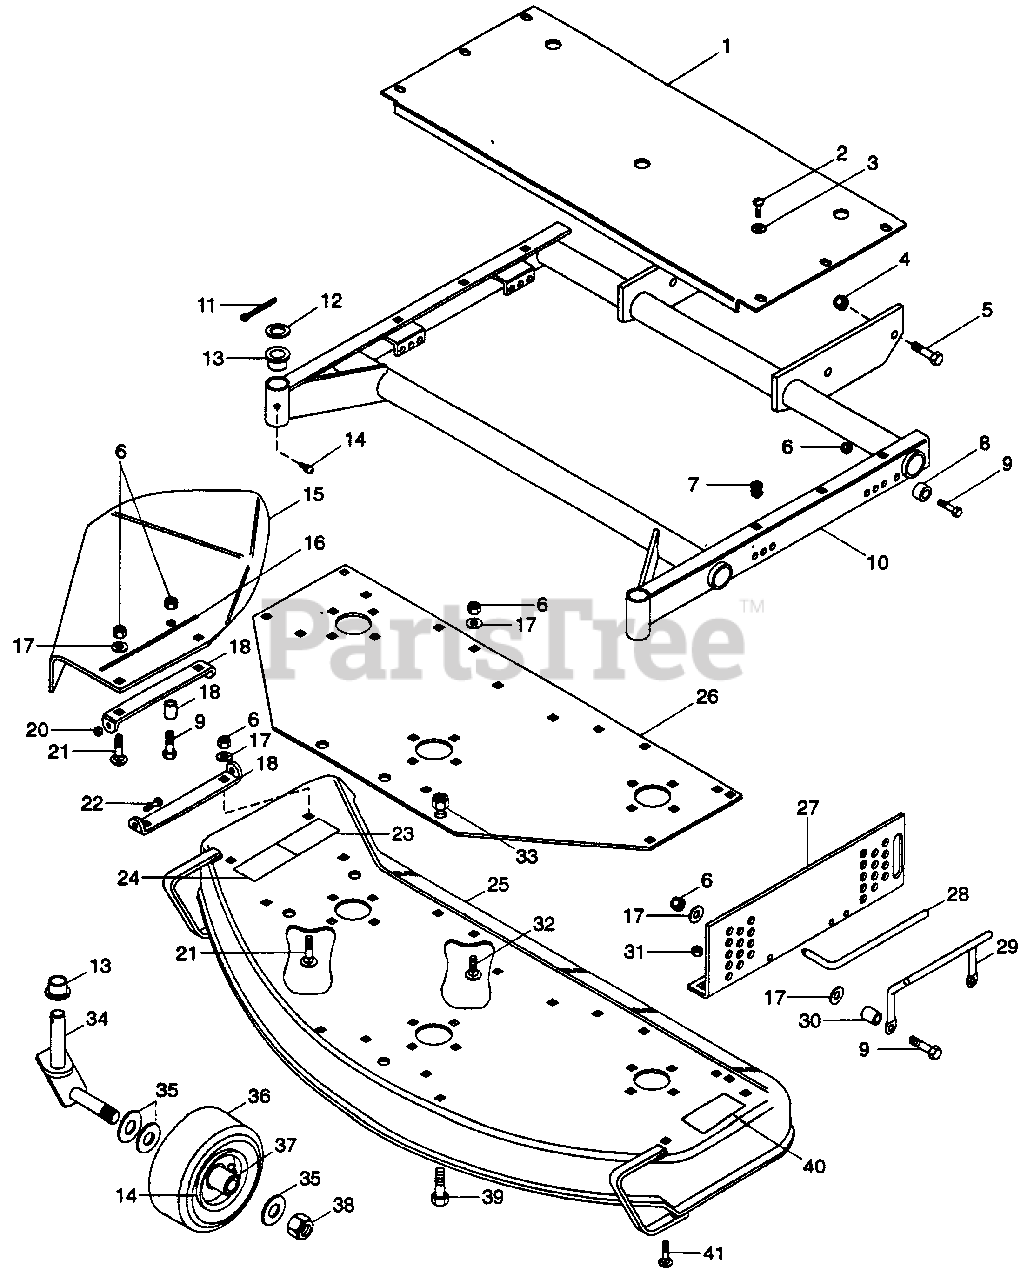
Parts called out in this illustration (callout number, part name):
1	GRD, 50" MOWER BELT
2	SCR-TAP .25-20 X .50 HXSLHD PL
3	WSHR-FL-STL .281 X .62 X .065
4	NUT-LK-NYL .625-11 PL
5	BLT-HEX .625-11 X 1.50
6	NUT-LK-NYL .375-16 PL
7	GRMT, PLASTIC
8	BUSHING .391 X .626 X .670
9	BLT-HEX .38-16 X 1.50 PL GR 5
10	WLDT, MOWER FRAME, 50", PRO 150
11	PIN-COTR .188 X 1.50
12	BRG-R-THRST 1.002 X 1.552 X .030
13	BSHG-FLG 1.020 X 1.385 X .75 X 1.75
14	FTG-LUBE .25-28 X .256
15	SHIELD, SFTY EXT 50" MWR
16	WIDTH OF CUT DECAL
17	WSHR-FL-STL .406 X .812 X .065 PL
18	BRKT, CHUTE
19	BSHG-SLV .407 X .625 X .750 PL
20	NUT-LK-NYL .250-20 PL
21	BLT-RDHDSQNK .38-16 X 1.0 PL
22	BLT-HEX .25-20 X .875
23	DECAL, DANGER HAND
24	DECAL, WARNING EYE
25	WLDMT, 50" MOWER DECK
26	PLT, SUPPORT
27	BRKT, MWR SIDE SPRT L.H.
27	BRKT, MWR SIDE SPRT R.H.
28	PIN, MOWER LOCKING
29	HANDLE
30	BUSHING
31	NUT-LK-NYL .312-18 PL
32	BLT-RDHDSQNK .38-16 X .75
33	NUT-LK-NYL .50-13 PL
34	WLDMT, CASTER FORK
35	WSHR-FLAT .812 X 1.469 X .134
36	WHL 9 X 3.50
37	BRG, BALL
38	NUT-LK-NYL INSR. .75-10 PL
39	BLT-HEX .50-13 X 1.25 PL GR 5
40	DECAL, DANGER FOOT
41	BLT, RDHDSQNK .31-18 X 1.0
